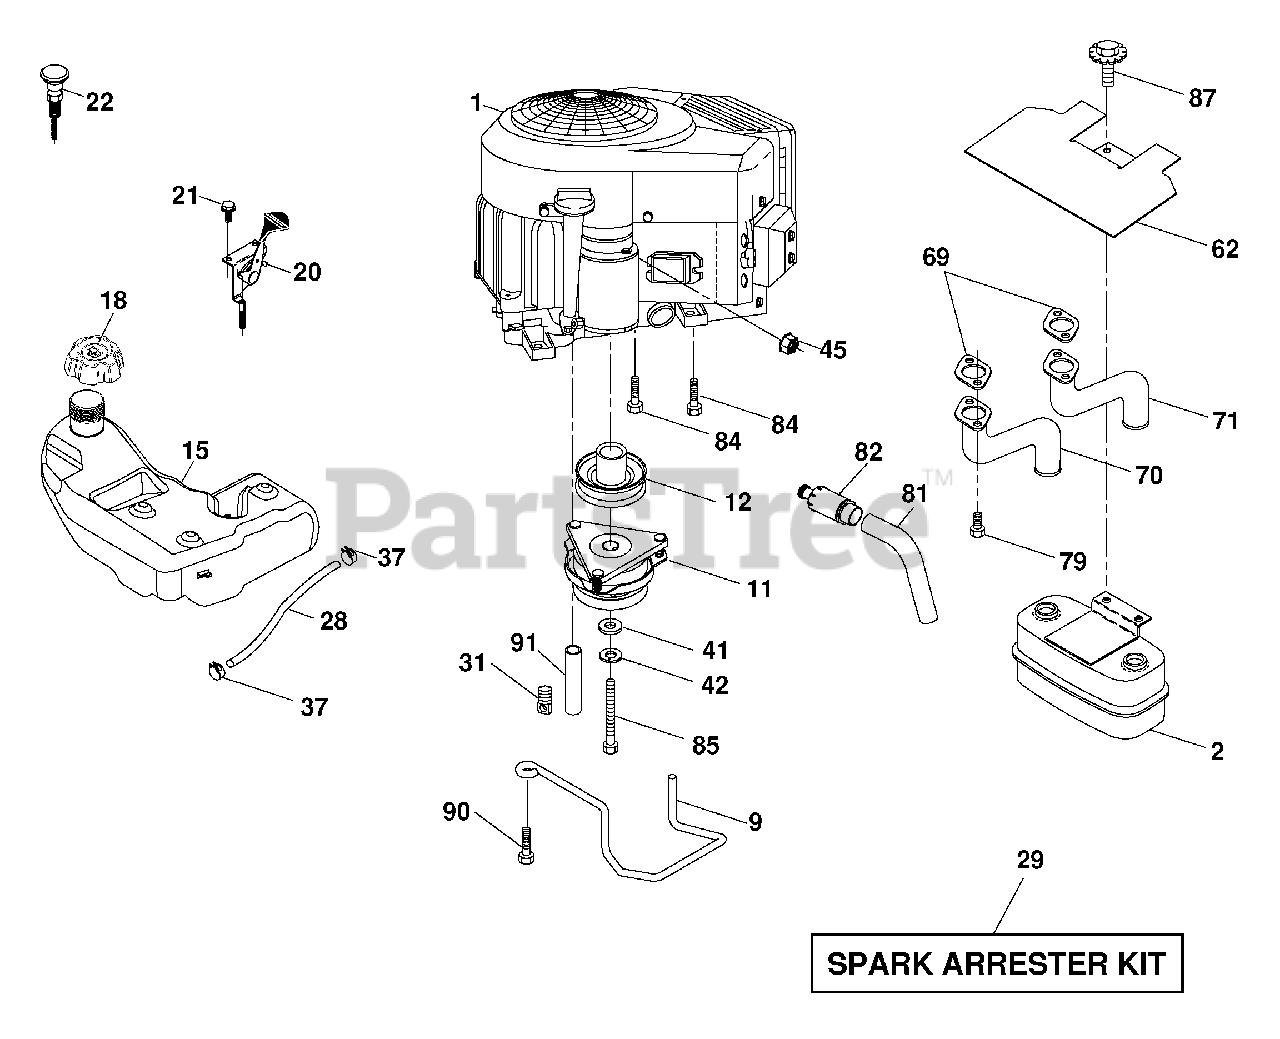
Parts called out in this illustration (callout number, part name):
2	Muffler
9	Keeper Asm. Belt Engine
11	Clutch Electric
12	Pulley Engine
15	Tank Fuel 4.0
18	Cap Asm
20	Control Throttle
21	Screw 10 x 3/4 Single Lead-Hex
22	Control Choke
28	Fuel Line
29	Spark Arrester Kit
31	Clip Push-In Hinged
37	Clamp Hose
41	Washer 1-1/2 OD x 15/32 ID x .250
42	Washer Lock 7/16
45	Nut Keps Hex 1/4-20 unc
62	Shield Heat Muffler
69	Gasket
70	Tube Exhaust LH
71	Tube Exhaust RH
79	Screw Socket Head
81	Tube Drain Oil Easy
82	Plug Drain Oil
84	Screw 3/8-16 x 1-1/2
85	Bolt Hex 7/16-20 x 3.75 Gr. 5
87	Bolt 5/16-18 unc x 1 w/Sems
90	Screw 3/8-16 x 1
91	Bushing 1.375 OD Heyco 2210
